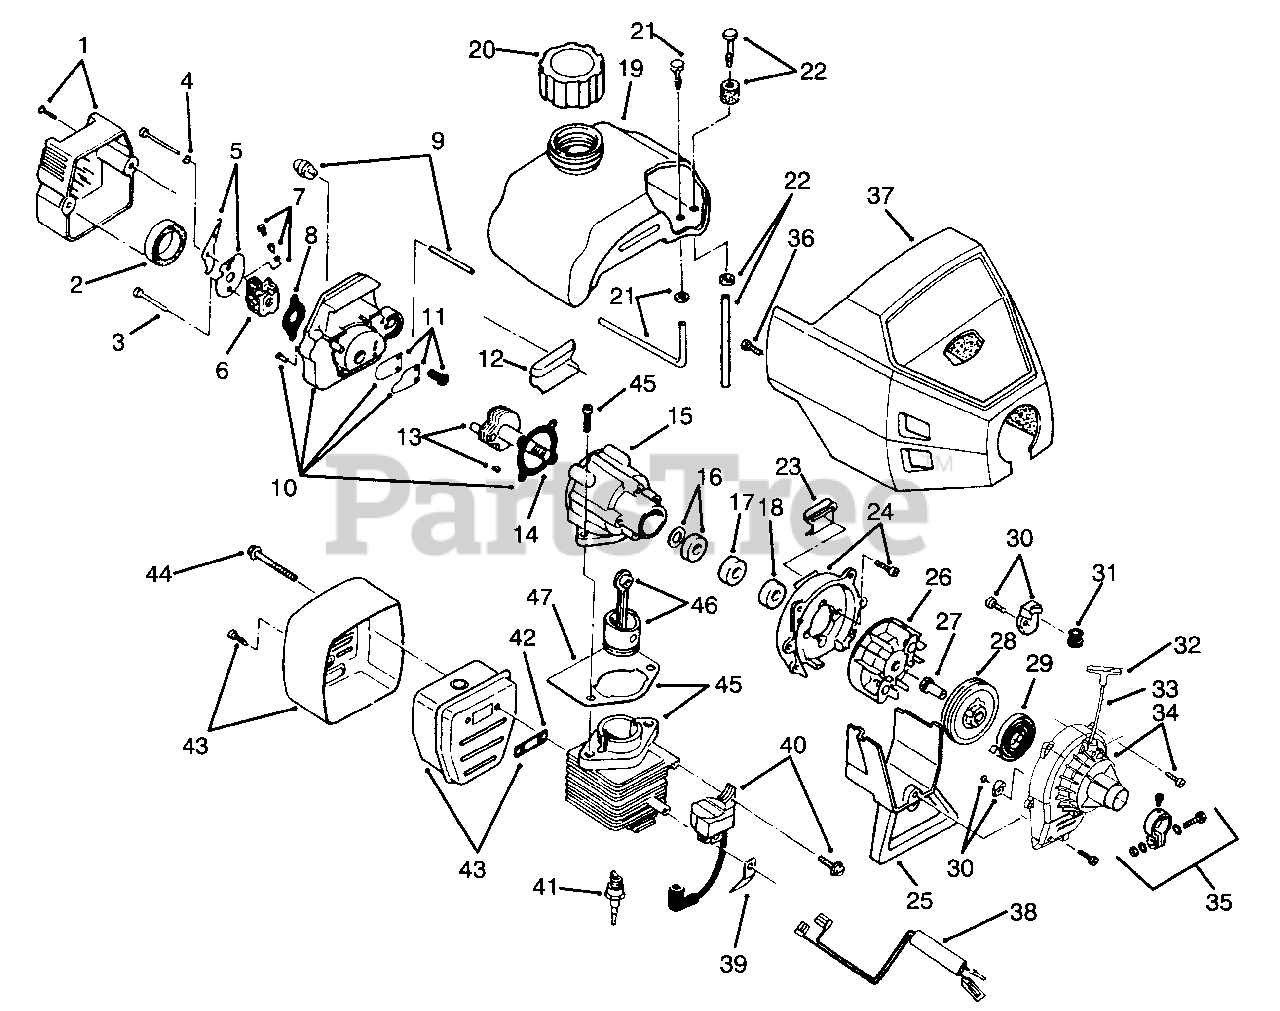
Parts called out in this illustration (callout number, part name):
1	Assy.-Carburetor/Air Clean. (Inc. Ref. No .2)
2	Filter-Air Cleaner
3	Screw-Carburetor
4	Washer-Wave
5	Choke-Lever and Plate
6	Assembly-Carburetor
7	Throttle Adj.-Walbro
8	Gasket-Carb. (10 Pack)
9	Assy.-Primer and Hose
10	Assembly-Carb. Mount (Incl. Ref. 11 & 12)
11	Assembly-Reed
12	Pad-Mounting,Rear
13	Assembly-Power Shaft
14	Gasket (10 Pack)
15	Assy.-Crankcase (Incl. Ref. No. 14-18)
16	Assembly-Inner Bearing
18	Assembly-Outer Bearing
19	Assemby-Fuel Tank (Incl. Ref. No. 20-22)
20	Assembly-Fuel Cap
21	Assembly-Return Line
22	Assembly-Fuel Line
23	Pad-Mounting, Front
24	Assembly-Shroud
25	Shroud Extension & Stand
26	Assembly-Flvwheel
27	Square Nut Drive
28	Assembly-Recoil Pulley
29	Spring-Recoil
30	Assembly-Pulley Retainer
31	Guide-Rope
32	Handle-Pull
34	Assembly-Starter Housing
35	Assembly-Upper Clamp
36	Engine Cover Screws
37	Assembly-Engine Cover
38	Assembly-Lead Wire
39	Ground Tab
40	Assembly-Module
41	Spark Plug
42	Gasket-Exhaust (10 Pack)
43	Assembly-Muffler
44	Bolt-Muffler Mounting
45	Assembly-Cylinder
46	Assy.-Piston and Rod
47	Gasket-Cylinder (10 Pack)
